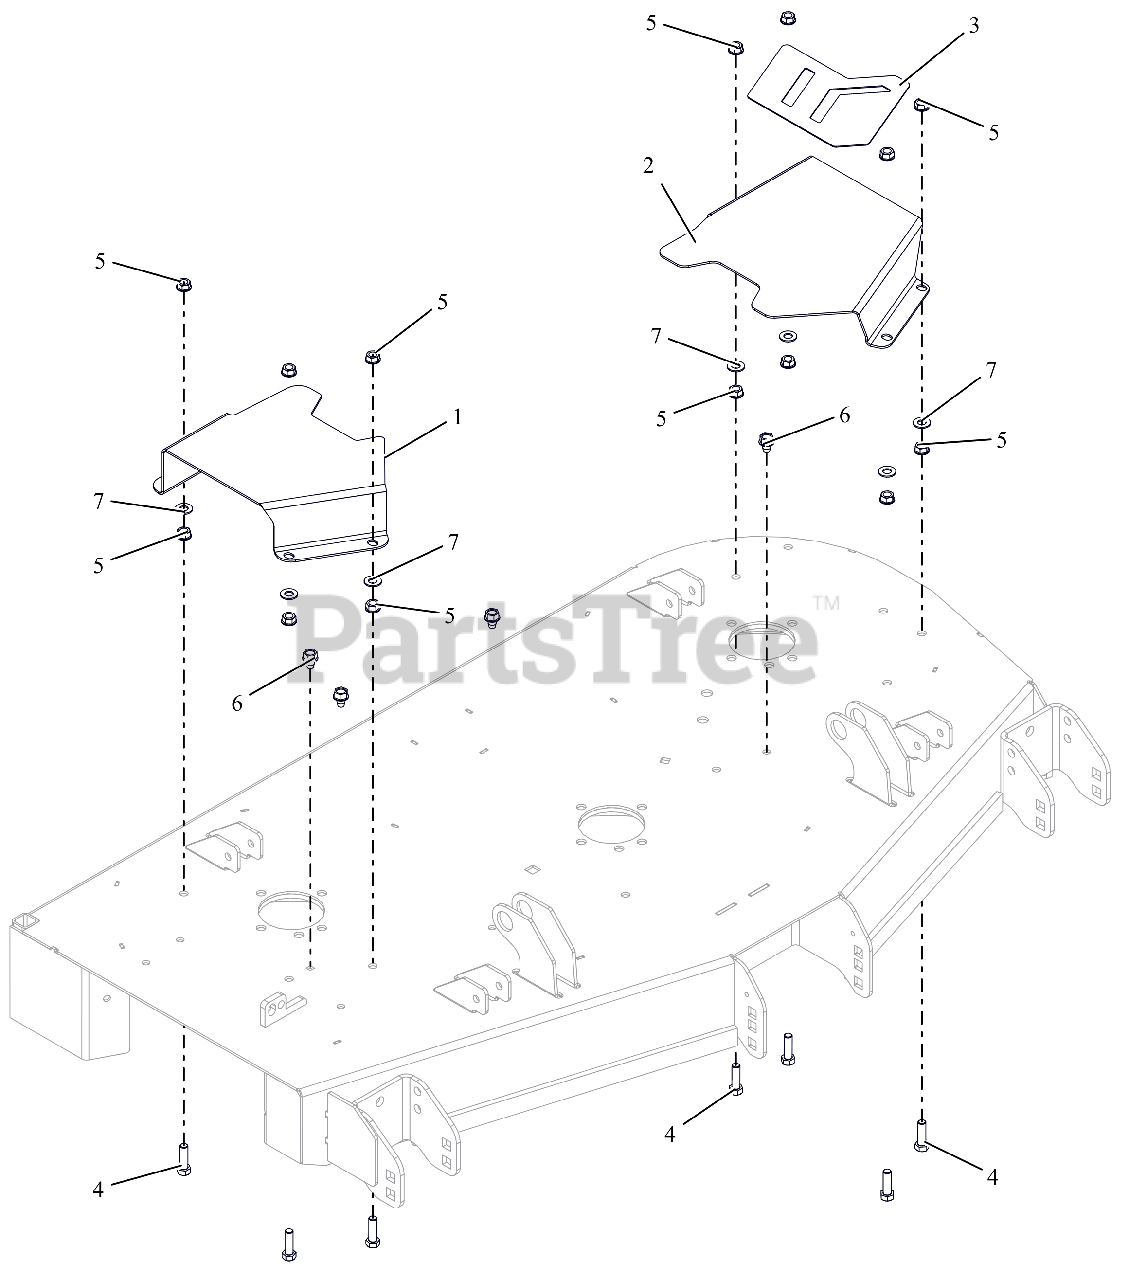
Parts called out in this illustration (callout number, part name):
1	COVER, BELT 48" RIGHT
2	COVER, BELT 48" LEFT
3	GRIP, TAPE 48 BELT COVER
4	BLT, HEX .38-16X1.25 G5 ZCC
5	NUT, SPNLK-FLG .38-16 G5 ZCC
6	SCR,TAP .375-16X.50 HWH TR ZCC
7	WSHR,FLT .406X.812X.065 ZCC
